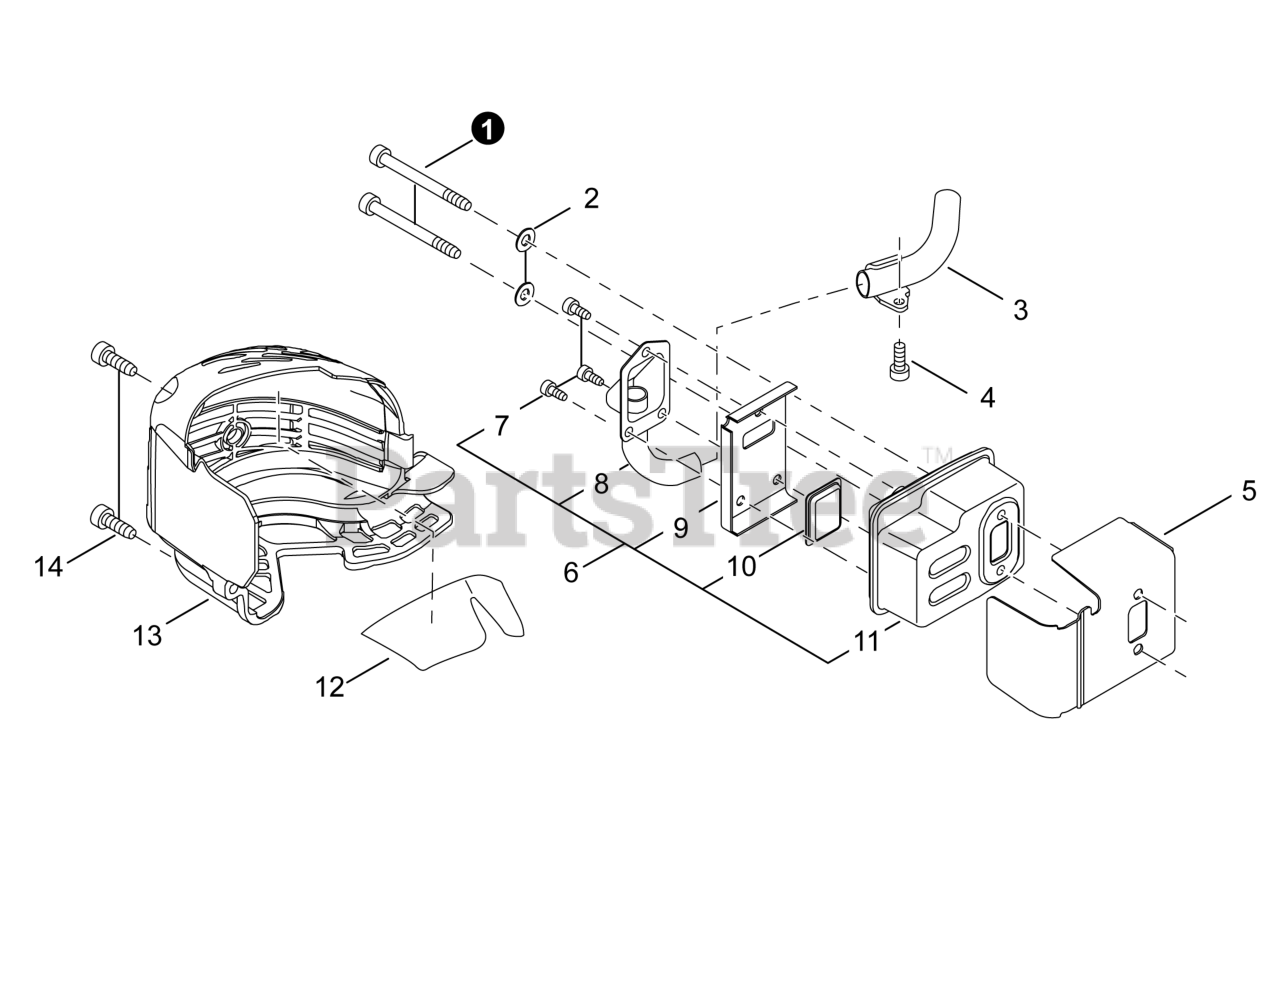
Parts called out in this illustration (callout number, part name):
1	BOLT, TORX 5x55
2	WASHER 5.5x12x0.8
3	GUIDE, EXHAUST
4	BOLT, TORX 5x10
5	HEAT SHIELD, EXHAUST
6	MUFFLER ASSY
7	BOLT, TORX 4x8
8	GUIDE, EXHAUST
9	GASKET, EXHAUST
10	SCREEN, SPARK ARRESTER
11	MUFFLER
12	PLATE, INSULATOR
13	COVER, MUFFLER
14	BOLT, TORX 5x16
